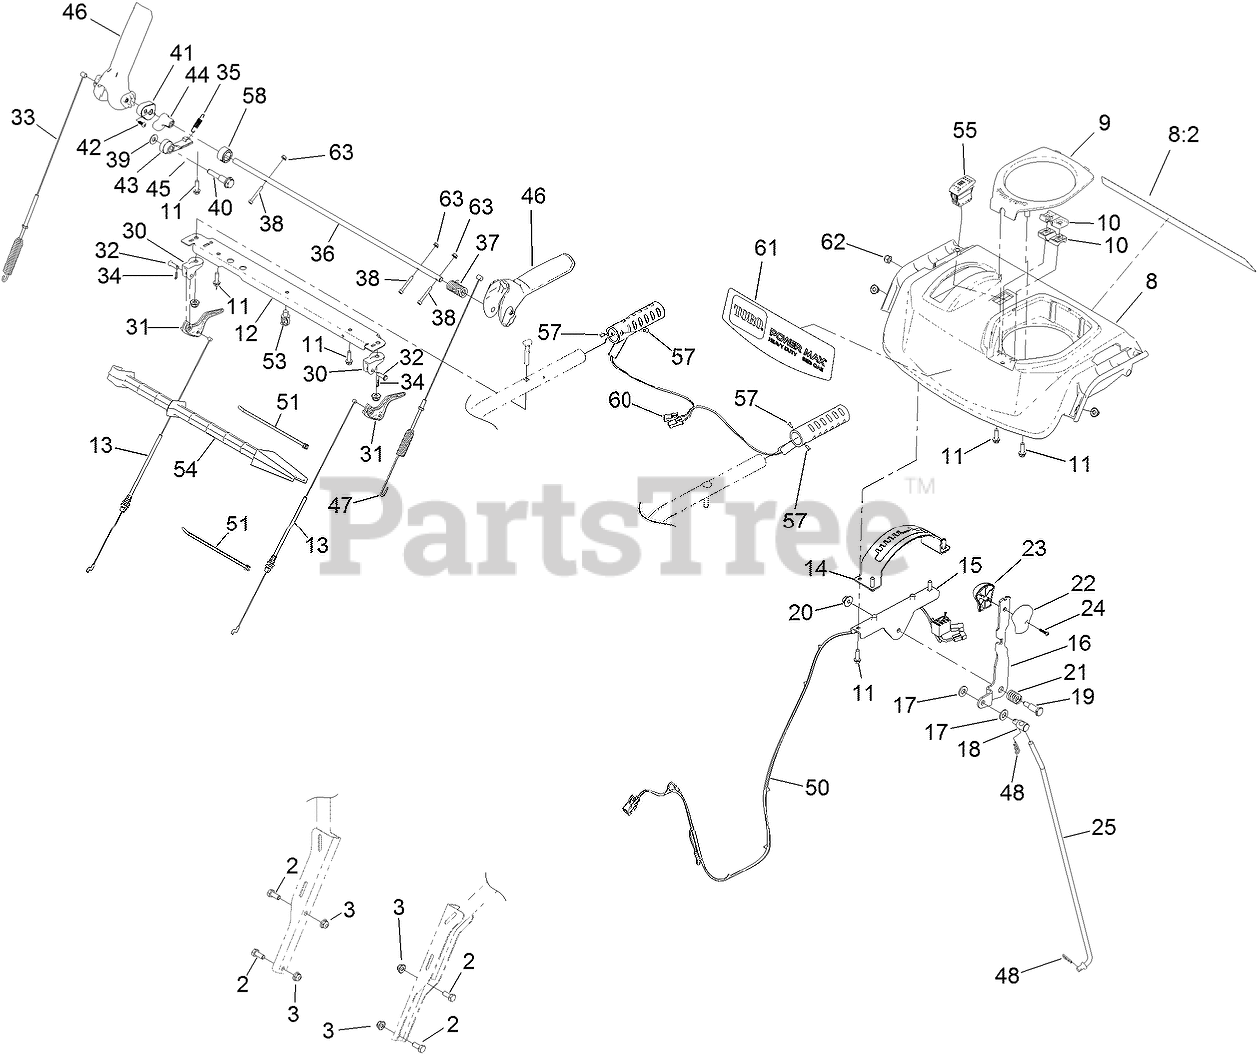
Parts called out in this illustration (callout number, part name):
2	SCREW-HH
3	NUT-HF
8	PANEL-CONTROL
8:2	DECAL-SAFETY
9	COVER-QUICKSTICK
10	SUPPORT-ROD
11	SCREW-PLASTITE, HWH
12	BRACE-CONSOLE
13	CABLE-CLUTCH
14	GATE-SHIFT
15	BRACKET-SHIFT
16	SELECTOR-SPEED
17	WASHER-FLAT
18	TRUNNION-ROD
19	SCREW-SHOULDER, HH
20	NUT-HF
21	SPRING-COMPRESSION
22	SHIFT KNOB ASM
22	KNOB-SHIFT, LH
23	KNOB-SHIFT, RH
24	SCREW-PPH
25	ROD-SHIFT
30	MOUNT-LEVER, CLUTCH
31	LEVER-CLUTCH
32	PIN-CLEVIS
33	CABLE-AUGER
34	PIN-HAIR
35	SPRING-LOCKOUT, HANDLE
36	ROD-LOCKOUT
37	SPRING-TORSION, HANDLE RETURN
38	SCREW-HSH
39	WASHER-FLAT
40	SCREW-SHOULDER
41	LOCK-HANDLE
42	SCREW-PPH
43	LATCH-LOCKOUT
44	CAM-LOCKOUT
45	LINK-LOCKOUT
46	LEVER-CONTROL
47	CABLE-TRACTION
48	PIN-HAIR
50	HARNESS-WIRE, LED AND HAND WARMERS
51	TIE-CABLE
53	CLIP-TIE
54	STICK-CLEANOUT
55	SWITCH-ROCKER, ON-NONE-OFF (HEATER)
57	RIVET-POP
58	COLLAR-CAM
60	GRIP-HEATED
61	DECAL-CONSOLE
62	NUT-HEX
63	NUT-LOCK ROHS
